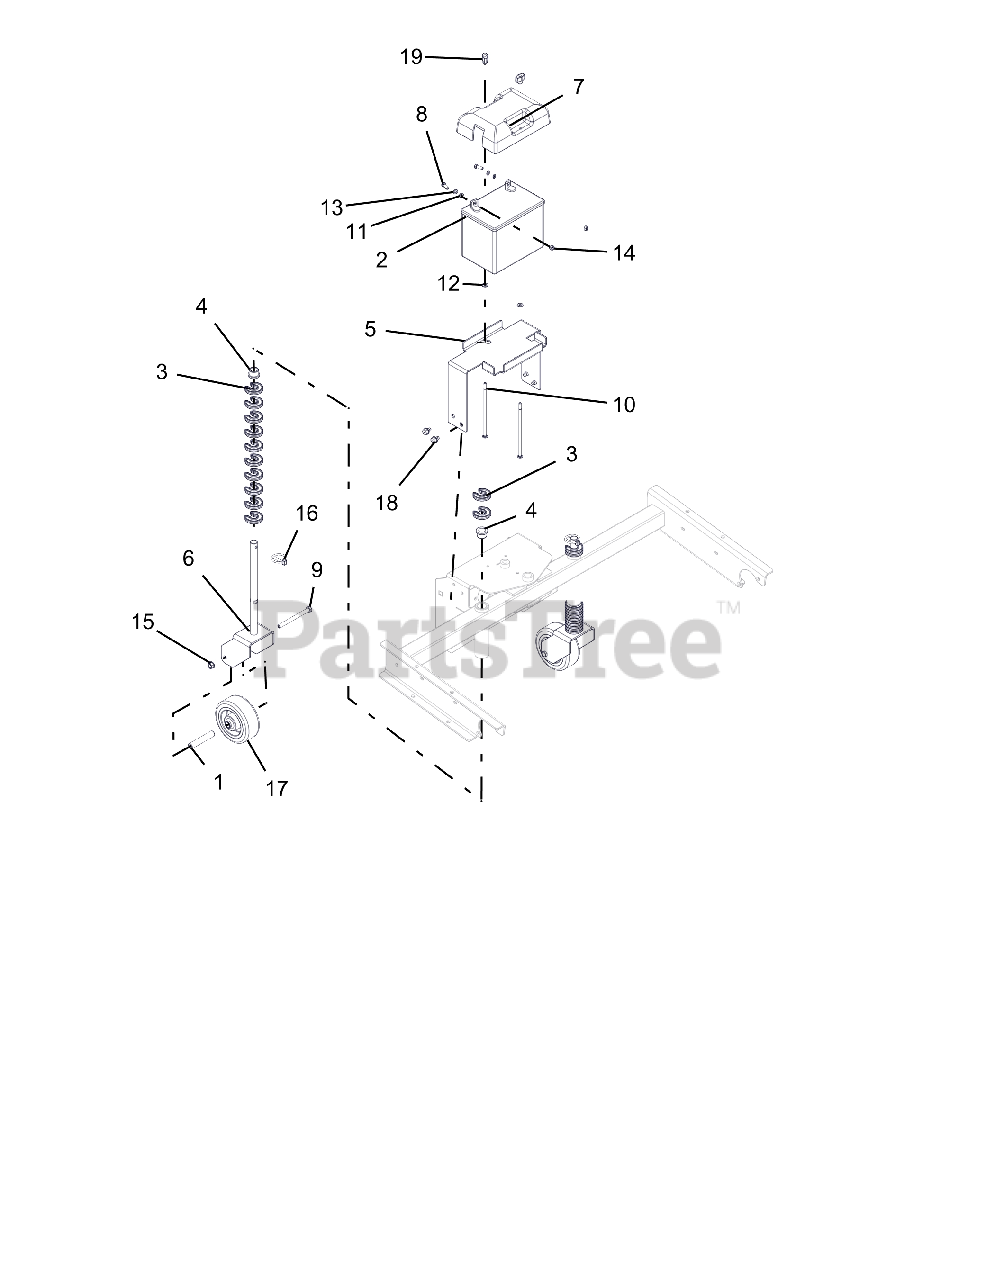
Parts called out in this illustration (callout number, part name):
1	SPACER, CASTER WHEEL
2	BATTERY, 300 CCA 10U1L
3	CLIP-HOC FIXED
4	BUSHING, FLANGE .75X.75X1.0
5	TRAY, BATTERY - POWER BRUSH
6	FORK, CASTER
7	COVER, BATTERY
8	@BLT-HEX .25-20X.75 GR5 YWZC
9	@BLT-HEX .38-16X4.50 GR5 YWZC
10	@BLT-RDHDSQNK .25-20X7.00 G2YZ
11	@WSHR-LK .25X.062 REG YWZC
12	@WSHR-FL-STL.281X.62X.065 YWZC
13	WSHR-FL-STL .265X.50X.087YWZC
14	@NUT-HEX .25-20 YWZC
15	@NUT-LK-TOP-FLG .38-16 YWZC
16	PIN, 1/4X1-9/16 LYNCH
17	WHEEL, CASTER - 5"OD
18	@SCR-TAP .38-16X.50 HWH TR YWZ
19	KNOB, WING - .25-20 UNC
